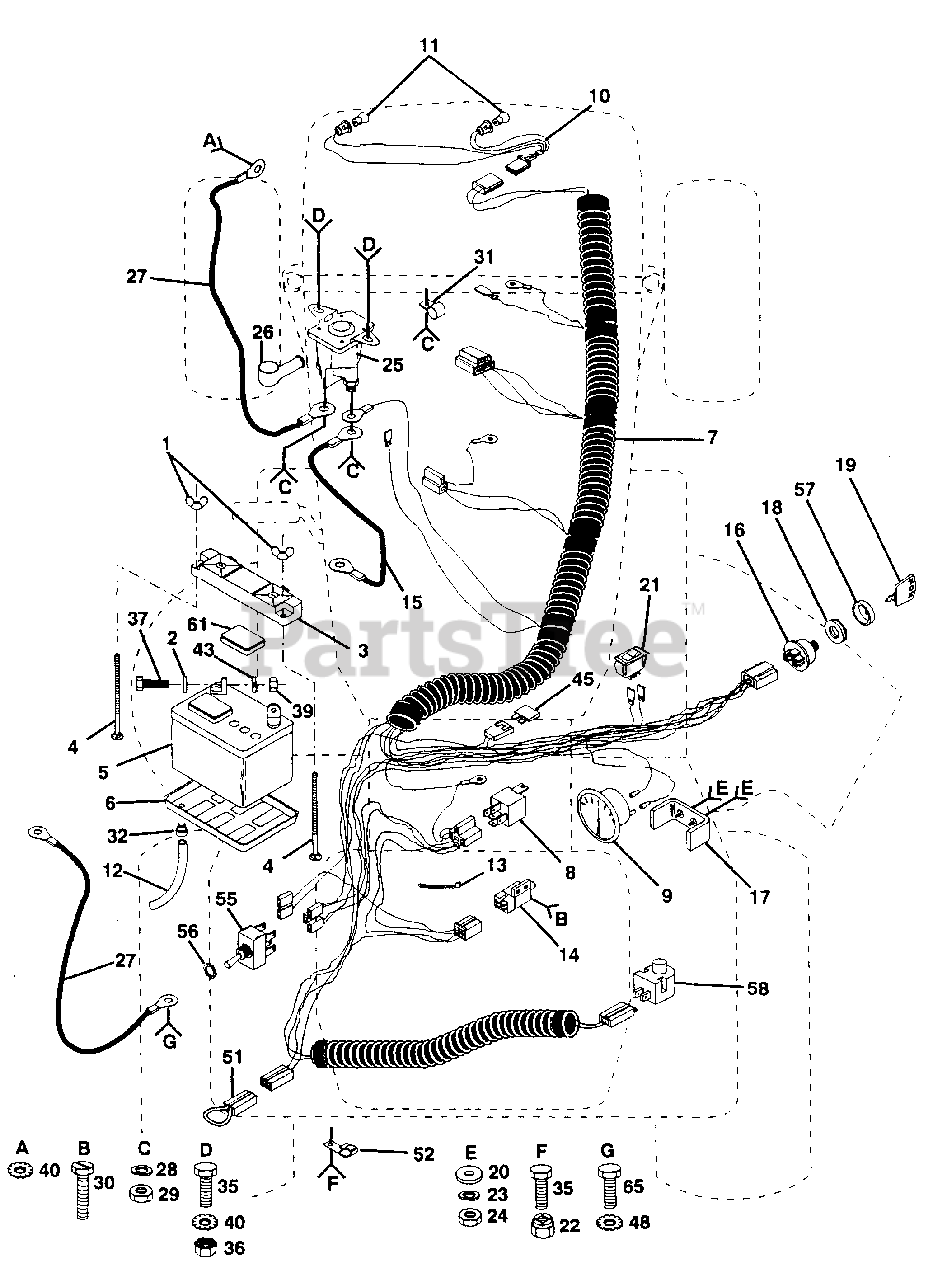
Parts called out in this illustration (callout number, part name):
1	Wing Nut 1/4-20 (AYP part number)
2	Washer 9/32 x 5/8 x 16 Ga (AYP part number)
3	Guard, Terminal (AYP part number)
4	Battery Bolt (Bolt, Carriage, Rd. Hd. Sq. Neck) 1/4-20 x 7-1/21 (AYP part number)
5	Battery (AYP part number)
6	Battery Tray (AYP part number)
7	Harness, Ignition
8	Relay (AYP part number)
9	Ammeter (AYP part number)
10	Harness, Light Socket (AYP part number)
11	Bulb, Light (AYP part number)
12	Tube, Battery Tray (AYP part number)
13	Cable Tie (AYP part number)
14	Switch, Interlock, Clutch (AYP part number)
15	Cable, Battery (Battery to Solenoid) (AYP part number)
16	Ignition Switch (AYP part number)
17	Bracket, Ammeter (AYP part number)
18	Nut, Ignition (AYP part number)
19	Key (AYP part number)
20	Washer 7/32 x 1/2 x 18 Gauge (AYP part number)
21	Switch, Light (AYP part number)
22	Nut, Crownlock 1/4-20 (AYP part number)
23	Washer, Lock (AYP part number)
24	Nut (AYP part number)
25	Solenoid (AYP part number)
26	Terminal Cover (AYP part number)
27	Cable, Battery (Battery to Ground) (AYP part number)
28	Washer, Lock (AYP part number)
29	Nut, Hex Jam 1/4 x 20 UNC (AYP part number)
30	Screw, Tap. Hex Hd. #10-24 UNC (AYP part number)
31	Clip, Fuel Line (AYP part number)
32	Clamp, Hose (AYP part number)
35	Bolt,Hex 1/4-20 x 1/2 Gr. 5 (AYP part number)
36	Nut, Keps, Hex 1/4-20 (AYP part number)
37	Bolt, Hex i/4-20 x 3/4 (AYP part number)
39	Nut, Hex 1/4-20 (AYP part number)
40	Washer, Lock 1/4 Ext. Tooth (AYP part number)
43	Washer, Lock 1/4 (AYP part number)
45	Fuse, 30 Amp. (AYP part number)
48	Washer, Lock, External Tooth 3/4 (AYP part number)
51	Loop, Wire Tiller Attachment (AYP part number)
52	Clip, Insulated (AYP part number)
55	Switch PTO (AYP part number)
56	Nut, Hex (AYP part number)
57	Bezel, Ignition (AYP part number)
58	Switch, Plunger (AYP part number)
61	Caps, Battery Set (AYP part number)
65	Bolt, Fin, Hex 3/8-16 UNC x 1 (AYP part number)
